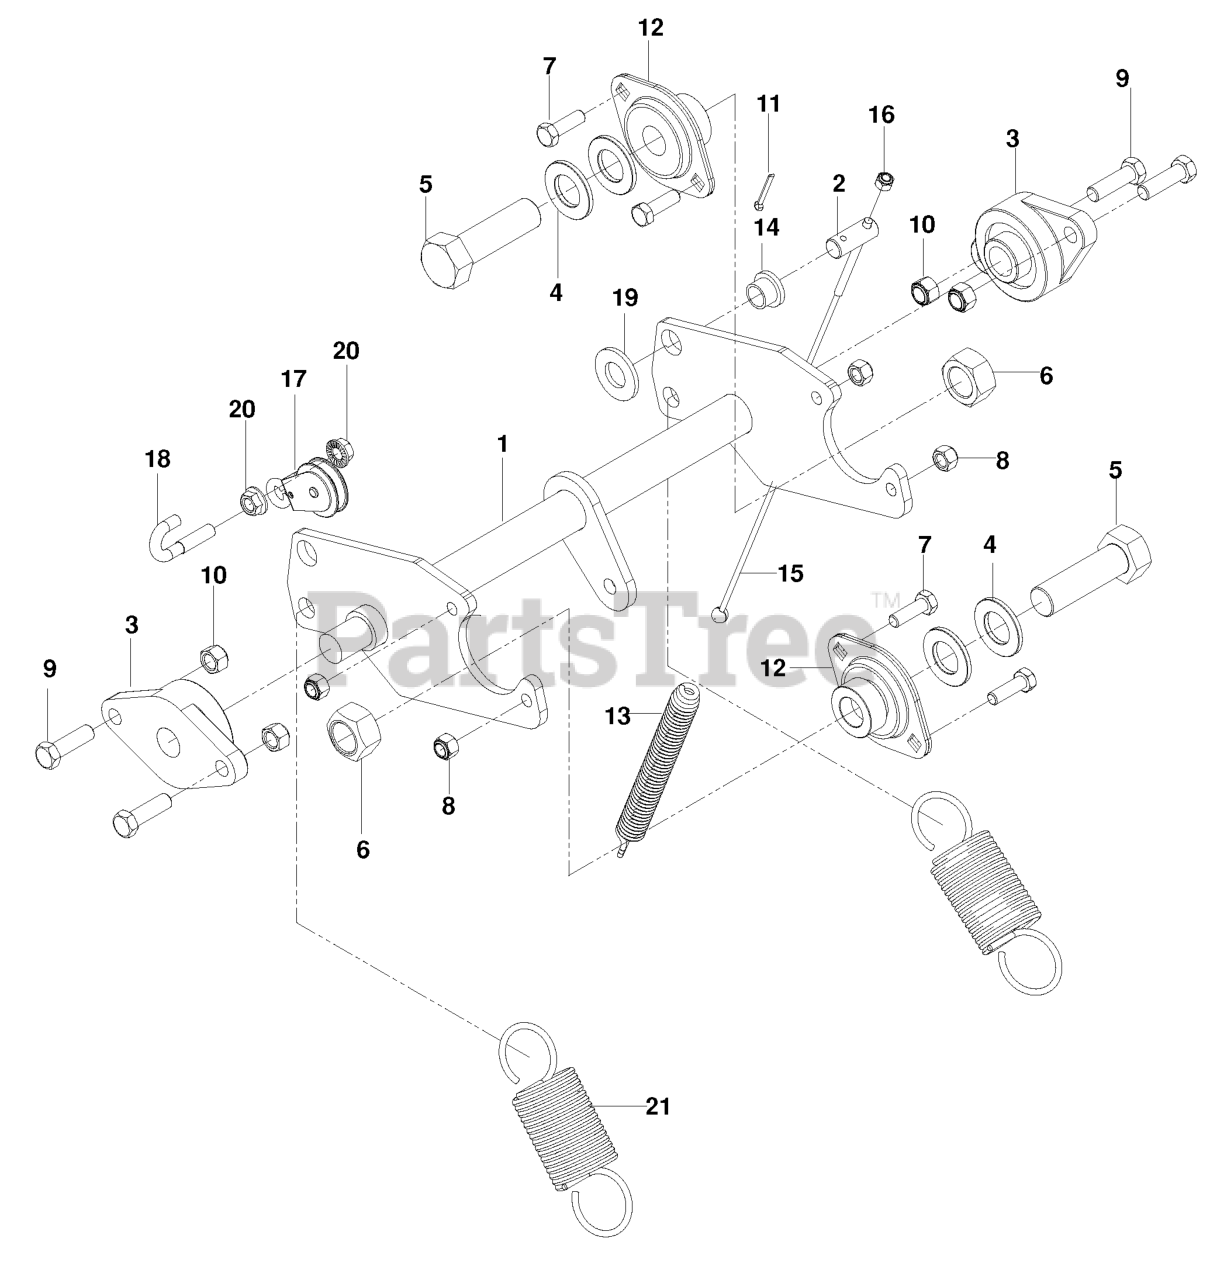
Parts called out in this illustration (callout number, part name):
1	TRUNNION SHAFT, BLACK
2	PIN - CABLE PIVOT
3	BEARING .75-2 BOLT
4	WASHER 3/4 FLAT SAE ZD
5	HCS 3/4-16 X 2-1/2 GR 5 ZD
6	NUT 3/4-16 HEX TOP LK ZD
7	HCS 5/16C X 1
8	NUT 5/16 NYLOC
9	HCS 3/8C X 1 1/4 GR5
10	NUT 3/8-16 NYLOC
11	PIN COTTER 1/8 X 1 ZD
12	FLANGE BEARING ZINC PLATED
13	SPRING - EXTENSION, CABLE
14	BUSHING, FLANGED NYLON
15	CABLE - PULL
16	NUT.1/4-20.HEX.NYLOC.ZD
17	BRACKET, PULLEY
18	J-BOLT
19	WASHER 5/8 FLAT
20	NUT 5/16C WHIZ
21	SPRING - EXTENSION
